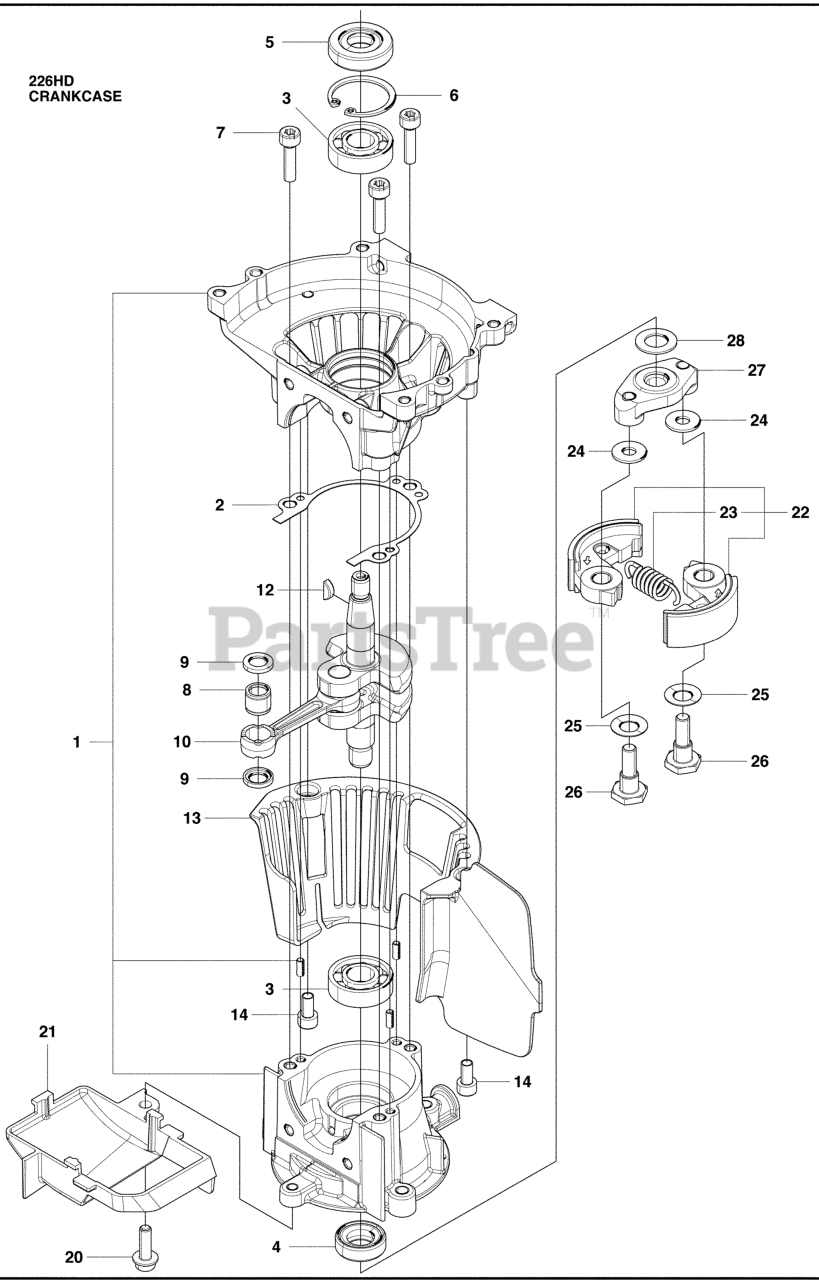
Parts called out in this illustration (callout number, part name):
1	CRANKCASE COMP
2	GASKET, CASE
3	BEARING
4	SEAL
7	RP BOLT TORX M5XL20 T27
10	CRANKSHAFT COMP
14	BOLT TORX M5XL10 T27
20	BOLT TORX
21	COVER ENGINE
27	PLATE CLUTCH
